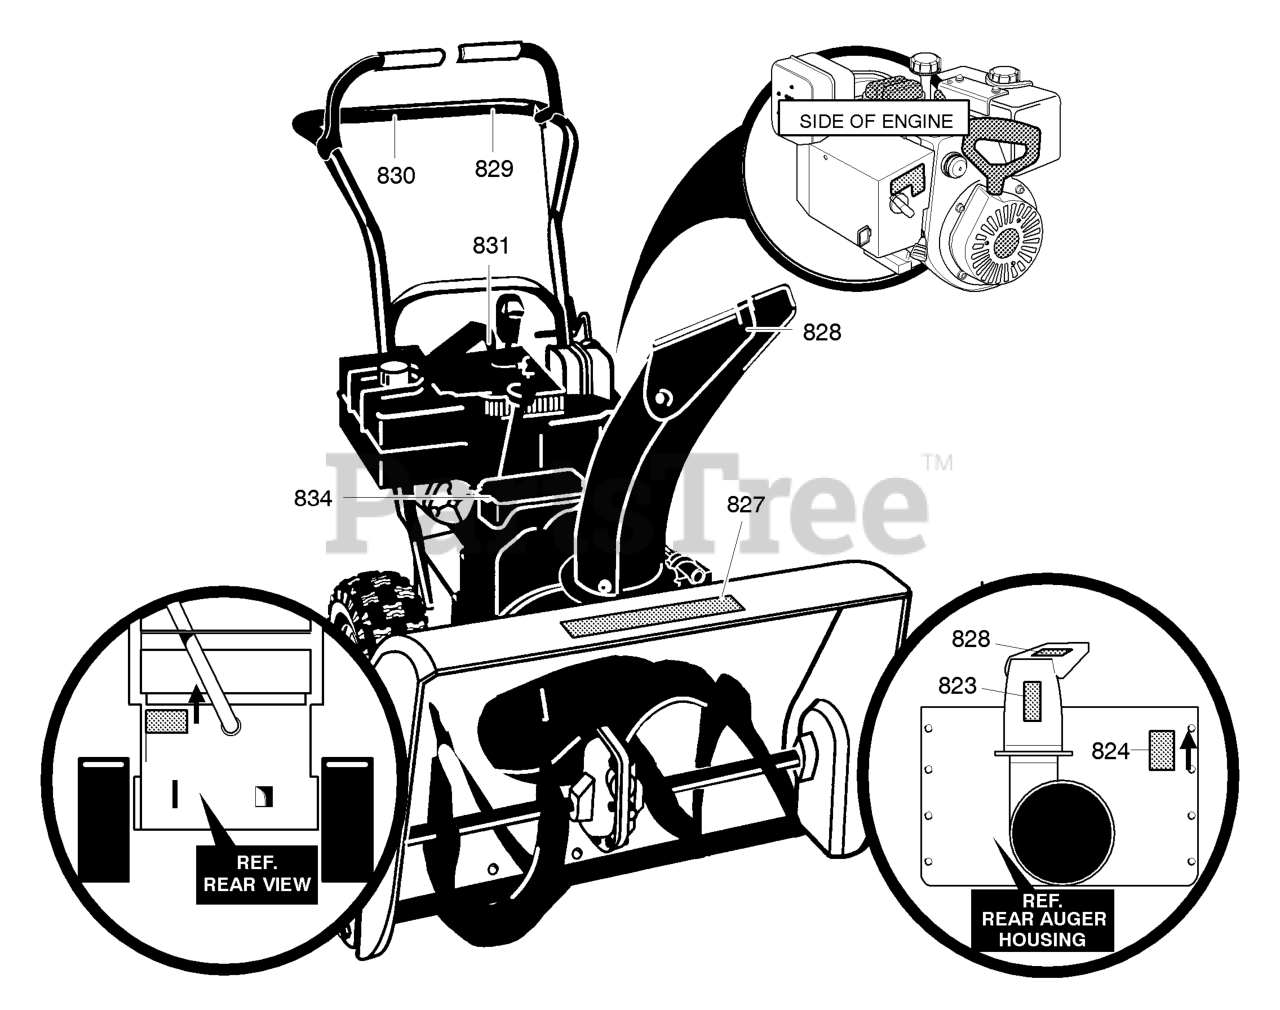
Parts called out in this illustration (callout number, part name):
823	DECAL, DANGER CHUTE HAND
824	DECAL, DANGER FOOT
827	DECAL, 9/24
828	DECAL, THROWN OBJECTS
829	DECAL, DRIVE CLUTCH
830	DECAL, AUGER CLUTCH
831	DECAL, GEAR SELECTOR
834	DECAL, TOOLBOX INFORMATION
835	DECAL, BRIGGS
